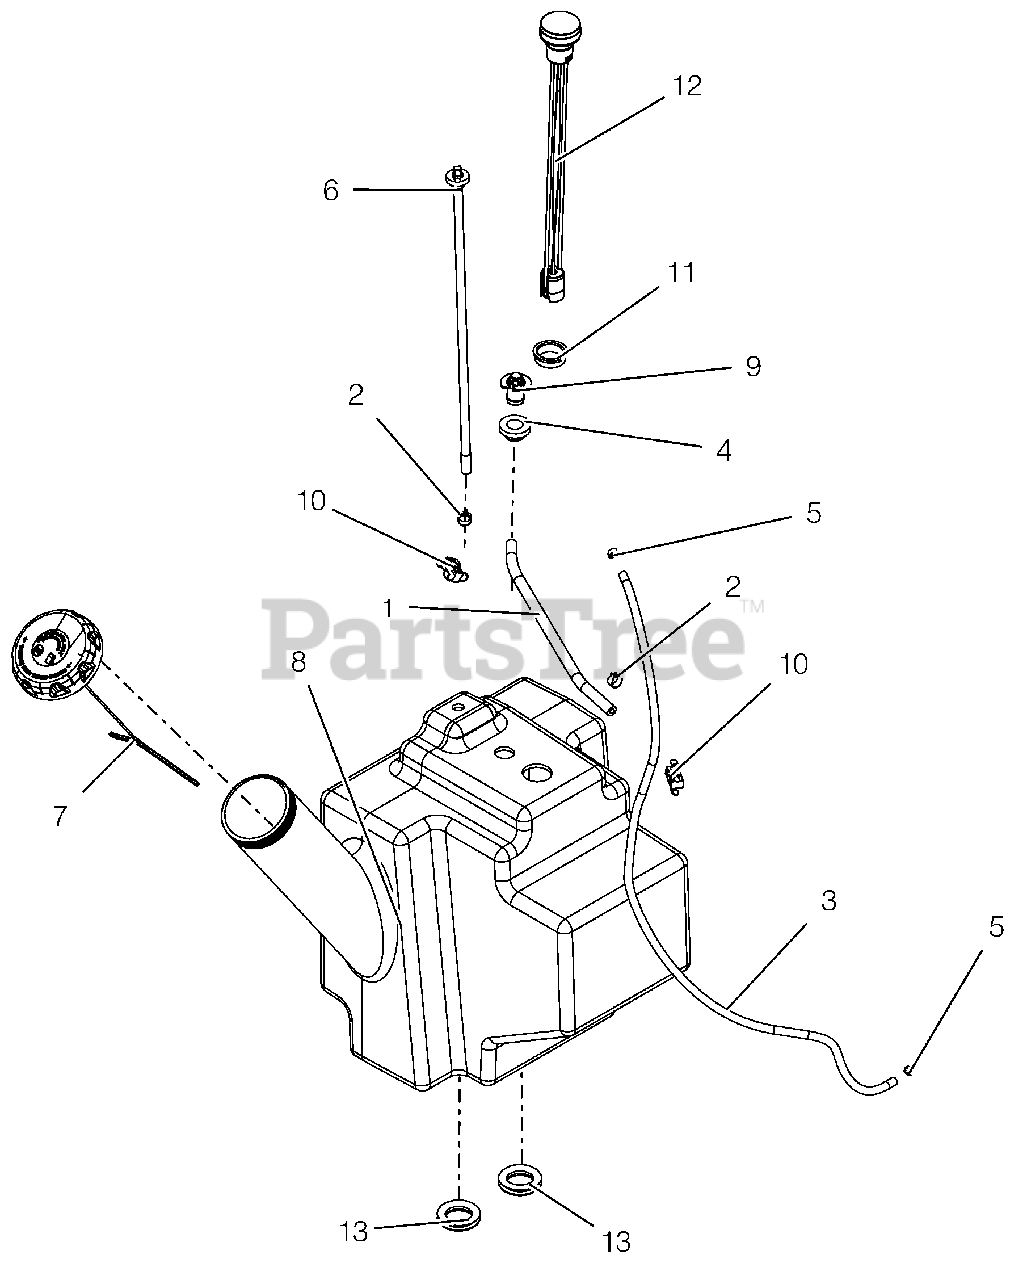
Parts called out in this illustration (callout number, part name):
1	HOSE, .25 LOW-PERM BULK GAS
2	CLAMP, FUEL LINE
3	HOSE, .188 LOW-PERM BULK GAS
4	GROMMET, REMOTE VENT NITRILE
5	CLAMP-HOSE, SPRING .188
6	ASS'Y, PROSTANCE FUEL PICK-UP
7	CAP, FUEL VENTIN AUTOLOCK
8	ASM, FUEL TANK
9	VALVE, 2-WAY
10	CLIP, T, .38-.50
11	GROMMET, FUEL GAUGE
12	GAUGE, REMOTE FUEL SEALED 15"
13	GROMMET 1.25ID X 1.5OD
